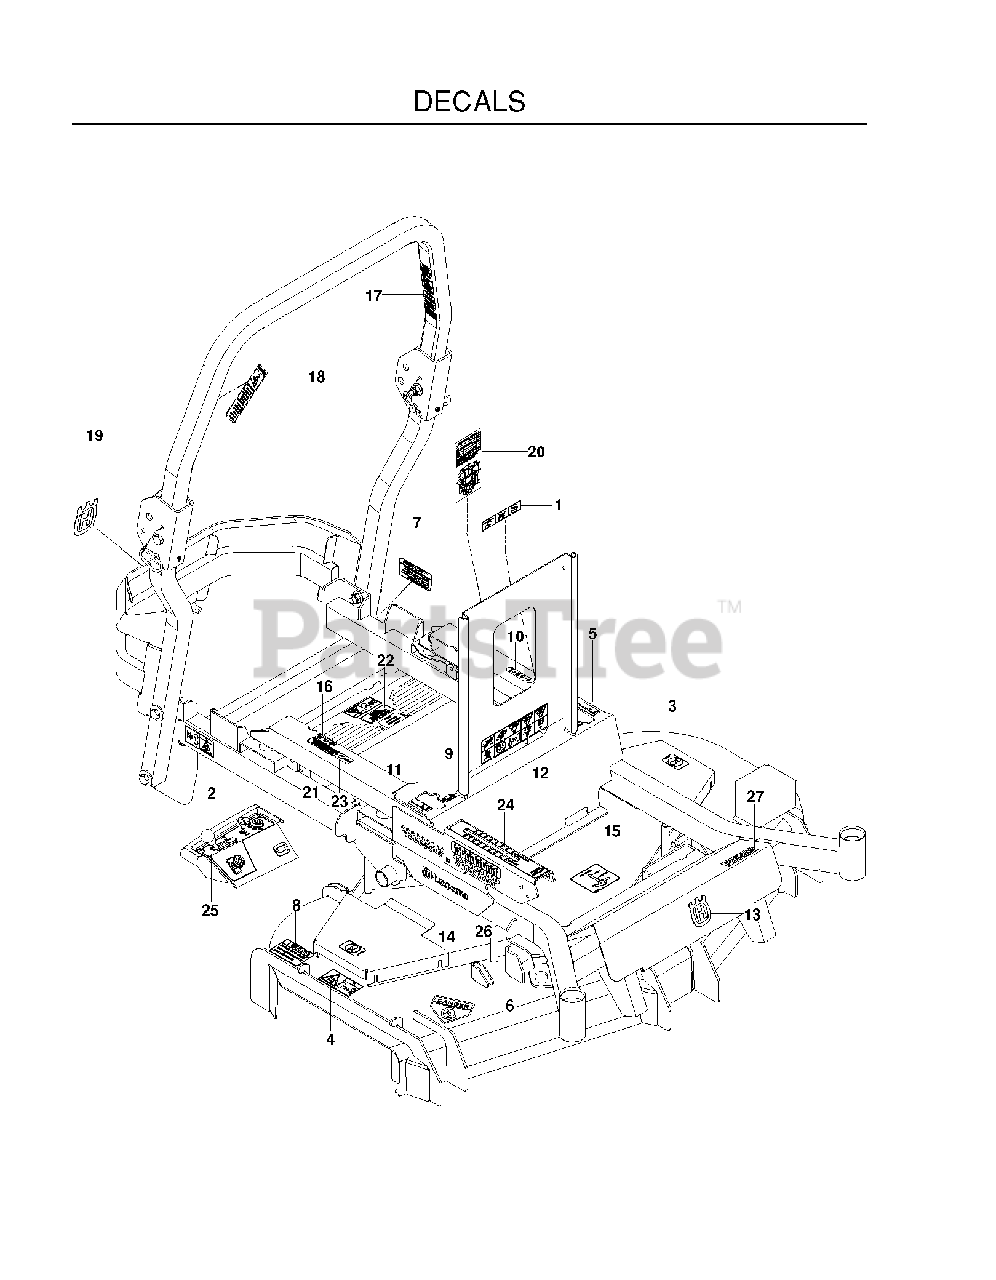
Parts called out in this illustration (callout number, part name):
1	EURO DECAL-BATTERY WARNIN6
2	DECAL, BELT DRIVE
3	DECAL, NO STEP
4	DECAL, EURO SEVERING
5	DECAL, MOTION CONTROL
6	DECAL, CPSC
7	DECAL, PROP. 65
8	DECAL, CAUTION
9	DECAL, F.S.T.
10	DECAL, PARK BRAKE
11	DECAL, OIL TANK
12	DECAL, WARNING
13	DECAL.AUGER.HUSQ.CROWN.SNOW
14	RP.DECAL.BADGE.170MM.TEXTLOGO
15	DECAL, BELT ROUTING
16	DECAL, FUSE
17	DECAL, ROPS
18	DECAL, ROPS, WARNING
19	DECAL, CROWN H, 110MM
20	DECAL, SERVICE
21	DECAL, WARNING SPARK ARRESTOR
22	HG_DECAL, ZT-5400
23	DECAL, ECM, AUSTRALIA
24	DECAL, HEIGHT
25	DECAL, CONTROL, GAS
26	DECAL, HEIGHT
27	DECAL.PZ34.
